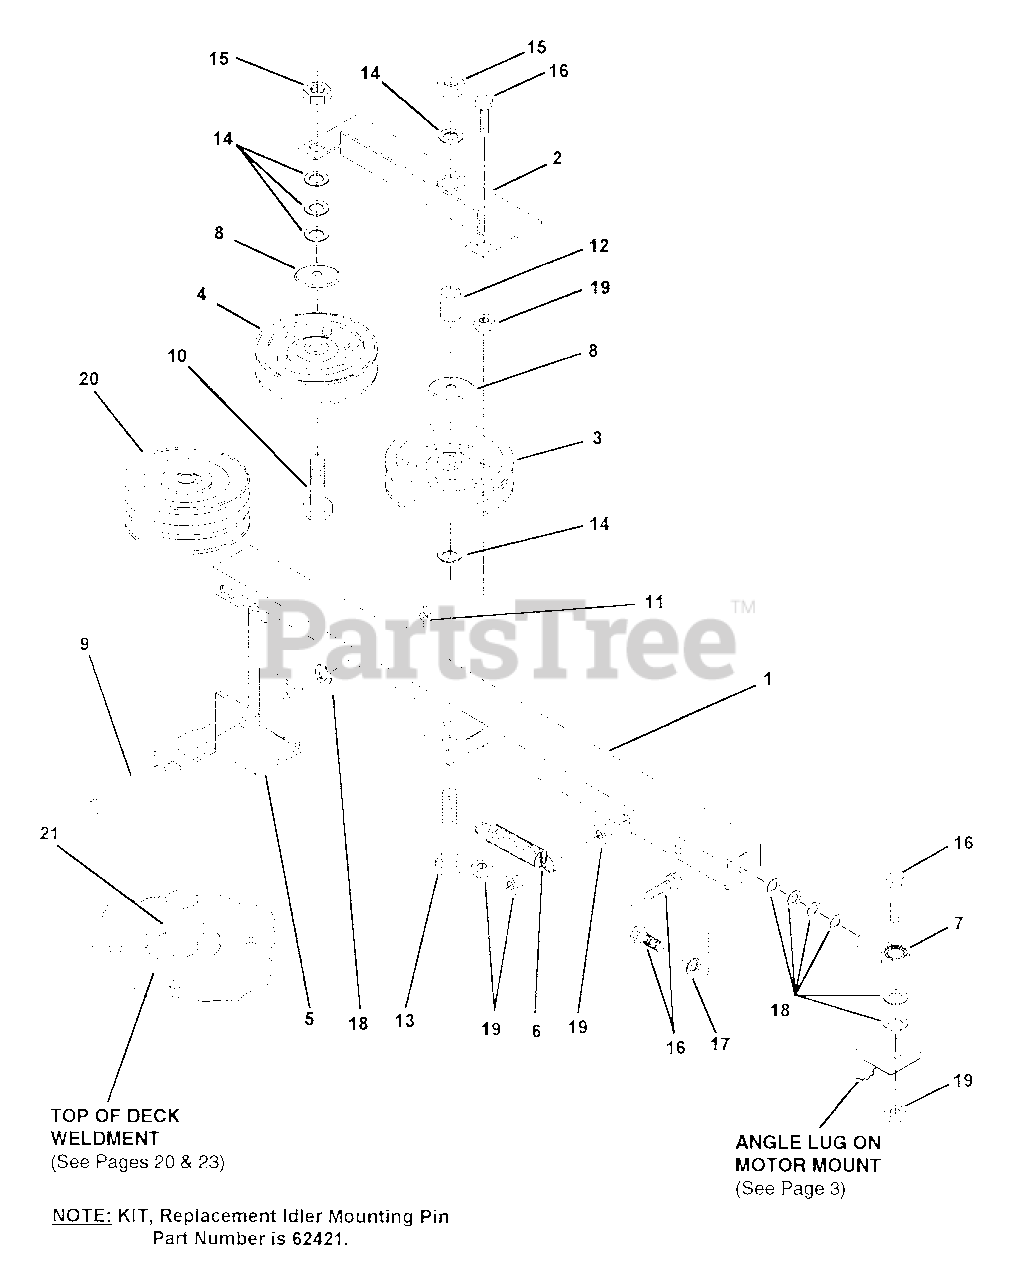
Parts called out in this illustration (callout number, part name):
1	CHANNEL WLDT, DOUBLE IDLER MNT
2	DOUBLE IDLER PIVOT WELDMENT
3	PULLEY FLAT IDLED 1/2 BORE 4"
4	PULLEY, V-IDLER, 4.48 O.D.
5	BRACKET, CHANNEL, MTG.
6	SPRING EXTENSION 3/4 X 4" OAL
7	BALL JOINT, 3/8-24 FEMALE PLAIN
8	WASHER, BEARING CAP
9	CLEVIS PIN, 3/8 2-3/4 O.A.L.
10	HH CAPSCREW, 1/2-13 X 2 L, GR 5
11	COTTER, RUE RING 5/16-3/8 PIN
12	BUSHING, IDLER M
13	CAPSCREW, 1/2-13 X 3
14	WASHER, FLAT, STD, 1/2
15	1/2"-13 LOCKNUT W/NYLOC
16	CAP SCREW, 3/8-24 X 1-1/4 GR.5
17	LOCK WASHER 3/8 HVY SPRING
18	WASHER, FLAT, STD, STEEL 3/8
19	LOCK NUT, 3/8 24 M-F LOCKNUT
20	PULLEY, 2 GROOVE, SPLIT STEEL
21	SPINDLE ASSEMBLY (48" OR 60" DECK)
